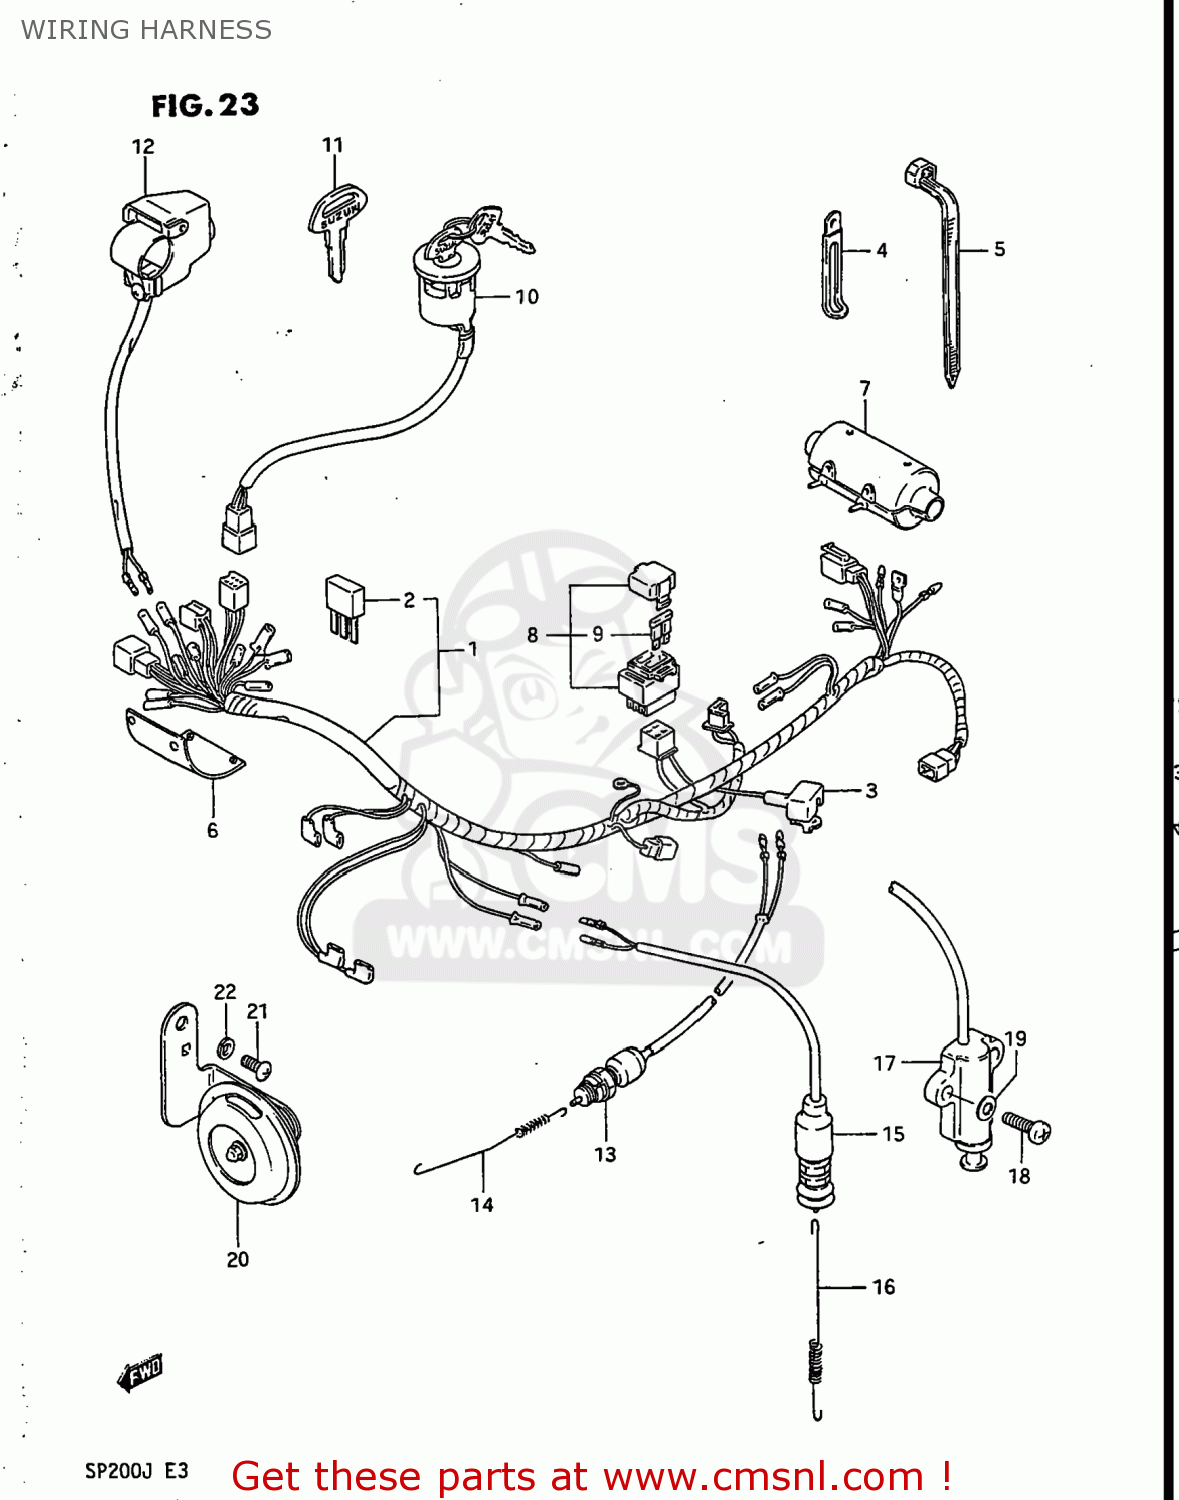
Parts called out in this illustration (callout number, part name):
1	HARNESS,WIRING
2	DIODE(STANLEY DE8804)
3	CAP,BATTERY TERMINAL
4	CLAMP
5	CLAMP(L:125)
6	BOOT,WIRING HARNESS
7	BOOT,WIRING HARNESS
8	BOX ASSY,FUSE
9	FUSE(15A)
10	SWITCH ASSEMBLY,IGNITION
11	KEY,BLANK
12	SWITCH ASSY,ENGINE STOP
13	SWITCH ASSY,STOP LAMP
14	SPRING
15	SWITCH ASSEMBLY,SIDE STAND
16	SPRING
17	SWITCH ASSEMBLY,SIDE STAND
18	SCREW
19	WASHER
20	HORN ASSY
21	SCREW
22	WASHER,LOCK
